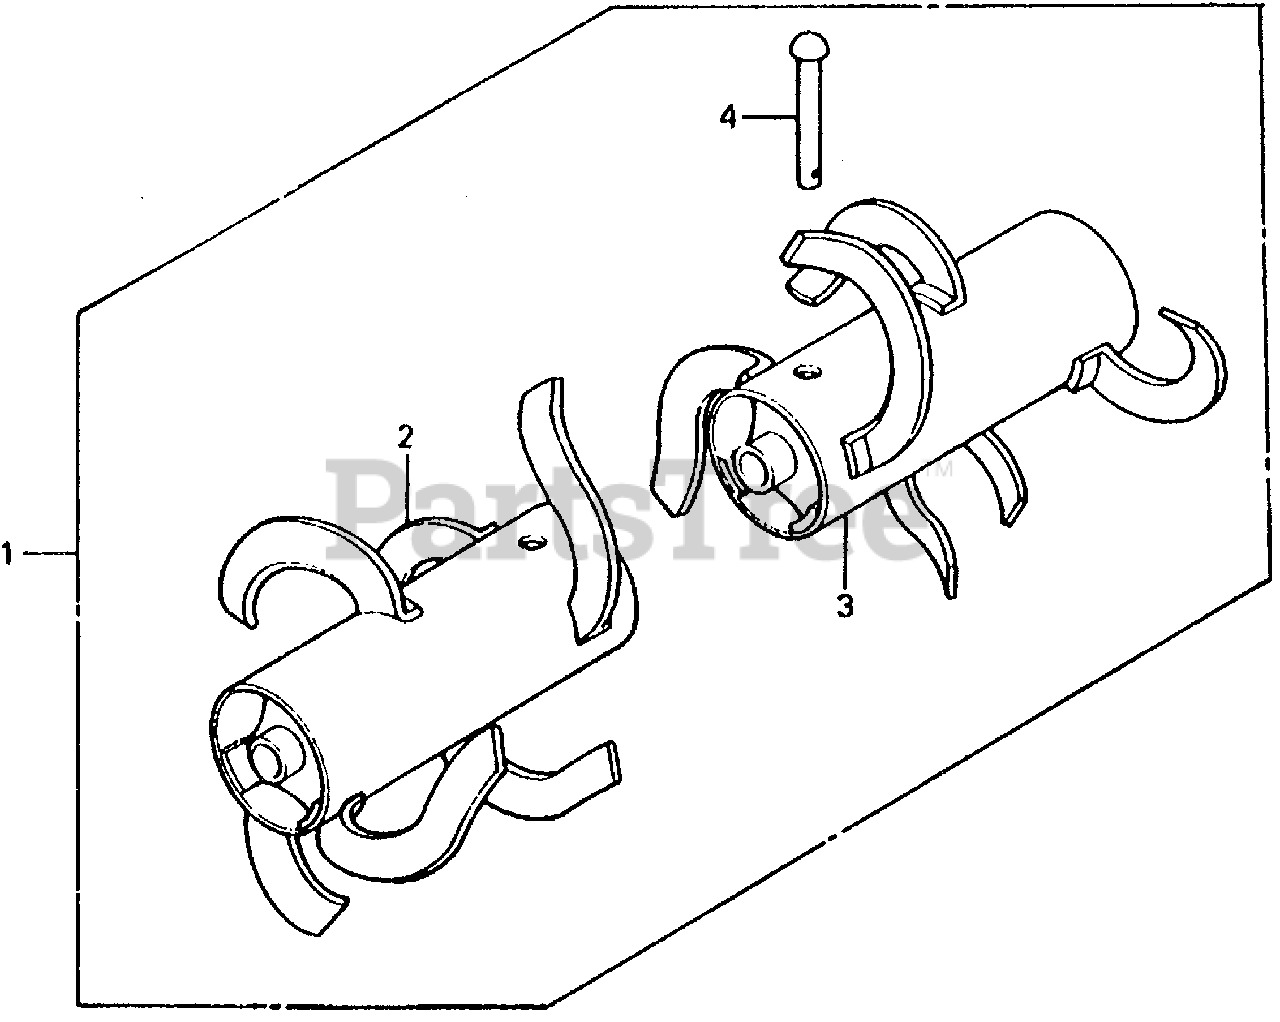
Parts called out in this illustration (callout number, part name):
1	ROTOR KIT, DRUM
2	ROTOR, R. DRUM
3	ROTOR, L. DRUM
4	PIN, DRUM ROTOR (8X100)
